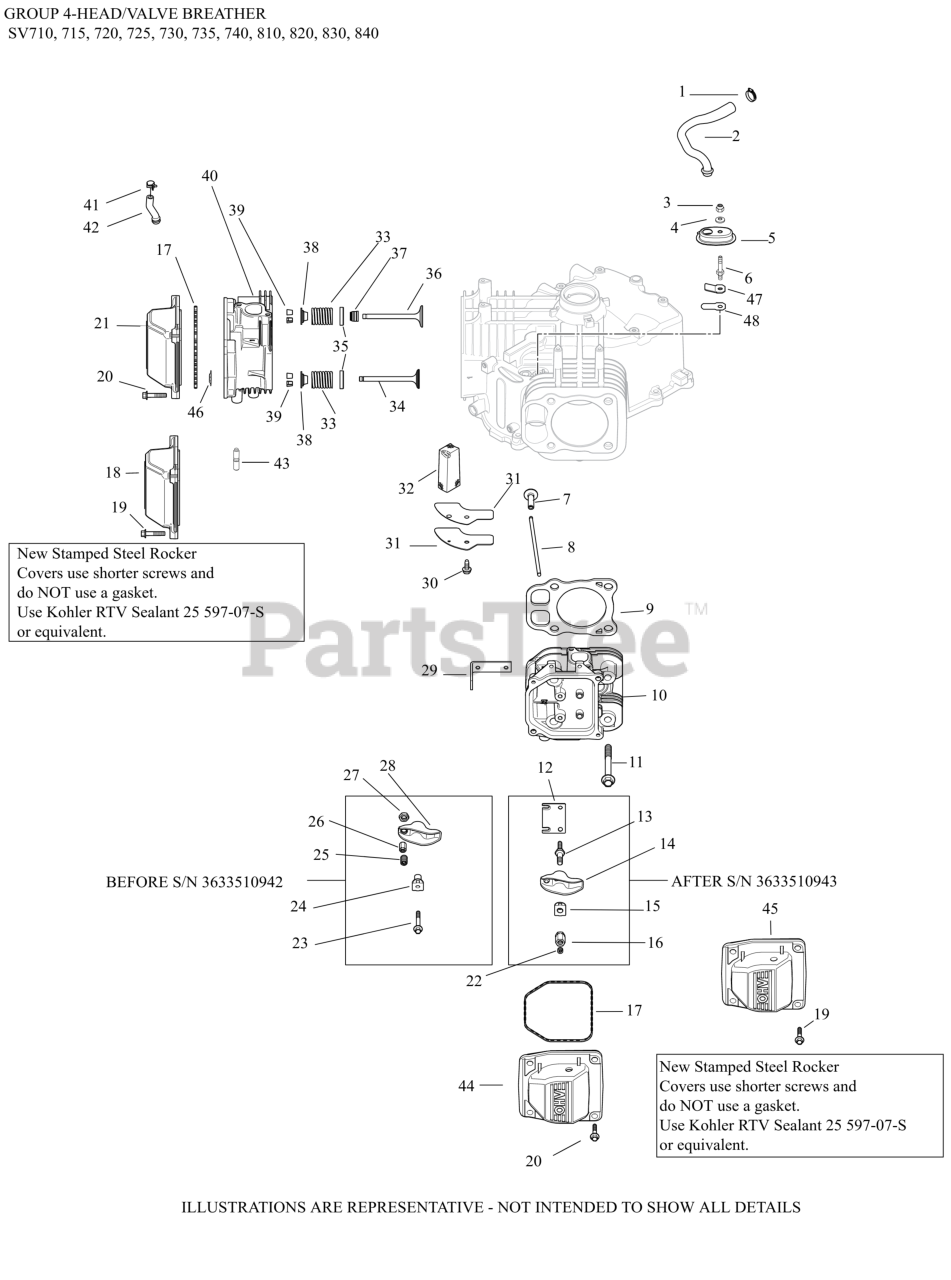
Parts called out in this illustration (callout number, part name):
1	CLAMP, HOSE (KM)-USE 25 237 31-S
2	KIT, BREATHER HOSE
3	NUT, LOCK M5X.8
4	WASHER, SEALING
5	KIT, BREATHER HOUSING
6	STUD, BREATHER COVER
8	ROD, PUSH
9	KIT, CYL HEAD GSKT (SV)-USE 32 841 02-S
10	KIT, #2 CYL HEAD ASSY-USE 32 318 20-S
11	SCREW, FLG M10X1.5X90
12	PLATE, GUIDE
13	STUD, ROCKER
14	ARM, ROCKER
15	PIVOT, ROCKER ARM
16	HEX NUT ASSEMBLY
17	O-RING (YELLOW), VALVE CO
18	COVER, ROCKER STAMPED STEEL
19	SCREW, PAN HEAD-(#25086660S)
20	SCREW, FLG M6X1.0X30
21	KIT, VALVE COVER-PLAIN (PLASTIC)
22	SCREW, SET
23	SCREW, FLG M6X1.0X45-USE 25 086 764-S
24	PIVOT, ROCKER ARM
25	SCREW, SET
26	NUT, HEX
27	NUT, M10X0.75
28	KIT, ROCKER ARM
29	STRAP, LIFT
30	SCREW,FLG THD FRM M6X1.0X16-(#25086397S)
31	GASKET, BREATHER COVER - DISC.
31	COVER, BREATHER
32	FILTER, BREATHER
33	SPRING, VALVE-USE 25 089 17-S
34	VALVE, EXHAUST (STD)-USE 32 016 01-S
34	VALVE, EXHAUST (.25)
35	RETAINER, SPRING
36	VALVE, INTAKE (STD)
36	VALVE, INTAKE (.25)
37	SEAL, VALVE STEM-USE 25 032 14-S
38	CAP, VALVE SPRING
39	KIT, RETAINER
40	KIT, #1 CYL HEAD ASSY-USE 32 318 19-S
44	KIT,BREATHER VALVE COVER (PLASTIC)
45	COVER, ROCKER (STEEL)- (#3275542S)
NI	RETAINER, VALVE GUIDE (KM)
